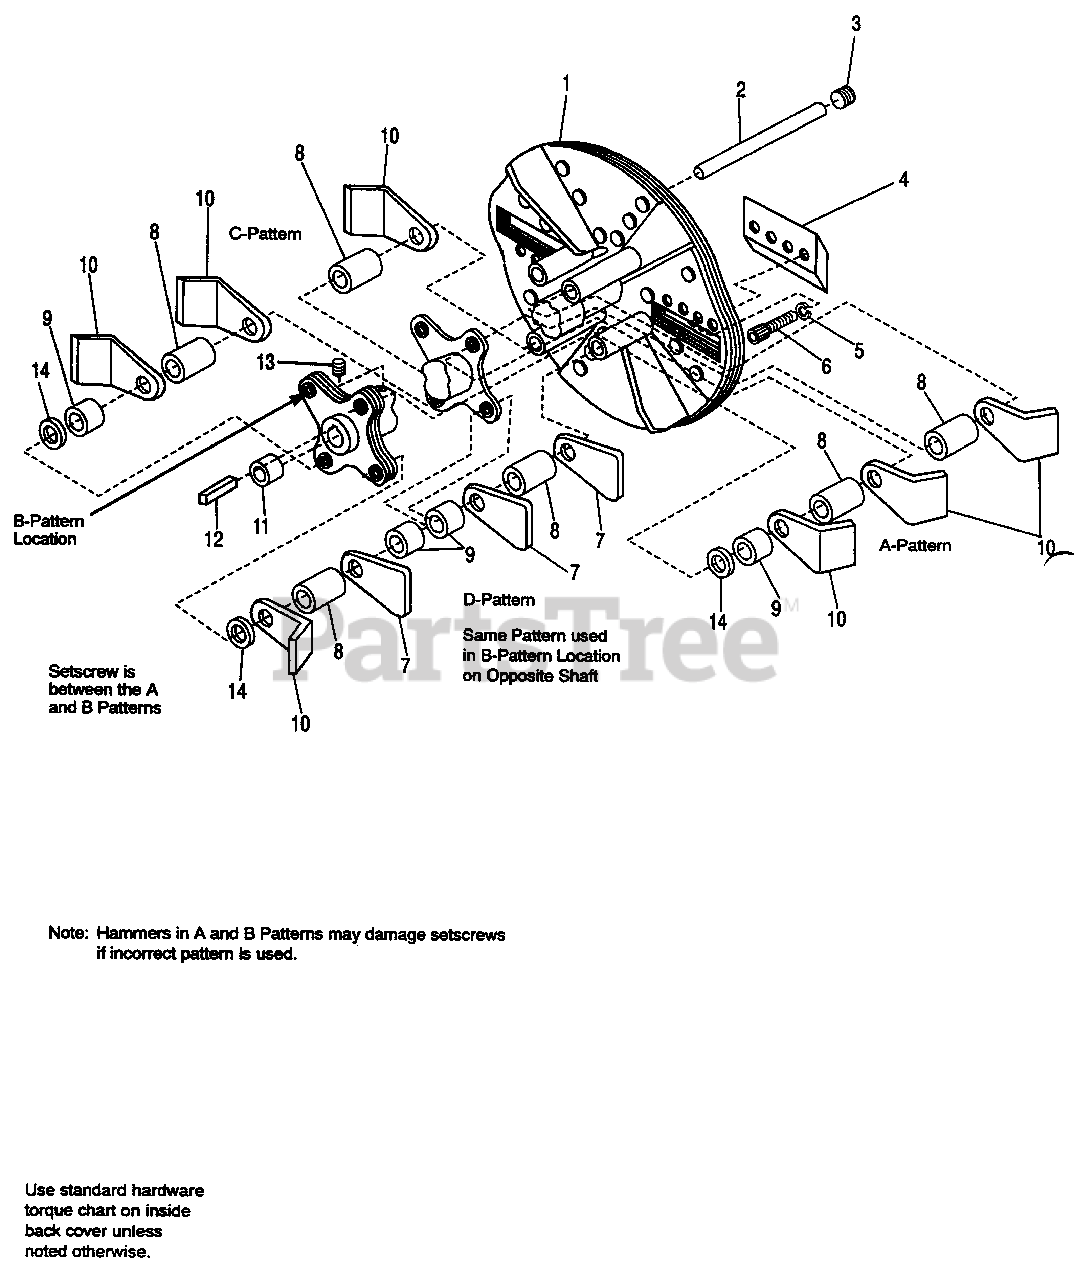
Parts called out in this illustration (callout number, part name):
1	ROTOR (PTO)
1	ROTOR (Trailer)
2	SHAFT, Hammer
3	PIPE Plug, Socket Head, 1/2"
5	LOCKWASHER, 1/2"
6	CAPSCREW, Socket Hd., 1/2-20 x 1-5/8
7	HAMMER, Triangular
8	SPACER, Long, 1-7/8"
9	SPACER, Short, 1"
11	SPACER, (PTO)
12	KEY, 3/8 x 3 3/8 (Trailer)
12	KEY, 8 mm x 56 mm (PTO)
13	SCREW, Set, 1/2-20 x 1/2 (Apply Loctite)
14	WASHER, 3/4 I.D. x 1-39/64 O.D. x 3/64 THK.
